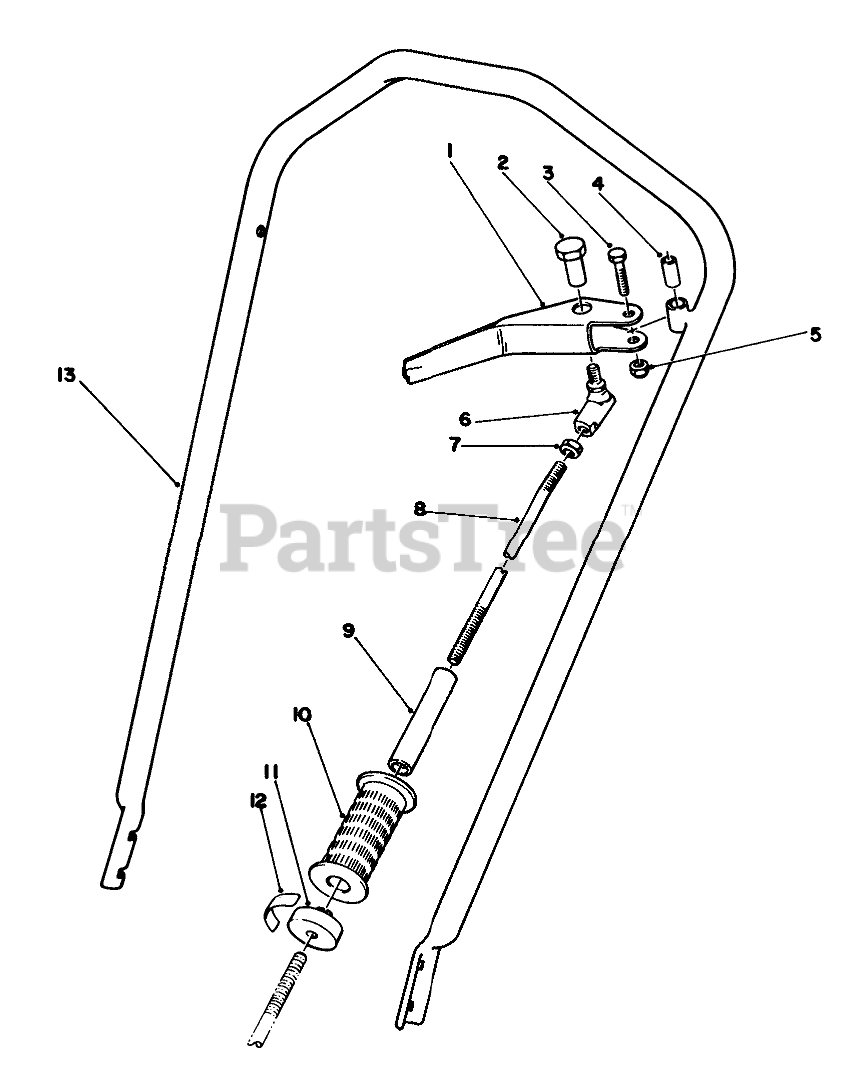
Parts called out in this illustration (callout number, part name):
1	CLUTCH CONT LEVER B
2	CONTROL LEVER BOLT
3	SCREW-HH
4	CONTROL LEVER BSHG
5	NUT-LOCK, NI
6	BALL JOINT
7	NUT-HJ
8	UPPER ROD LINKAGE
9	ADJ. TURNBUCKLE O
10	HANDLE GRIP
11	LOCK KNOB O
12	DECAL
13	HANDLE TUBE ASM BO
